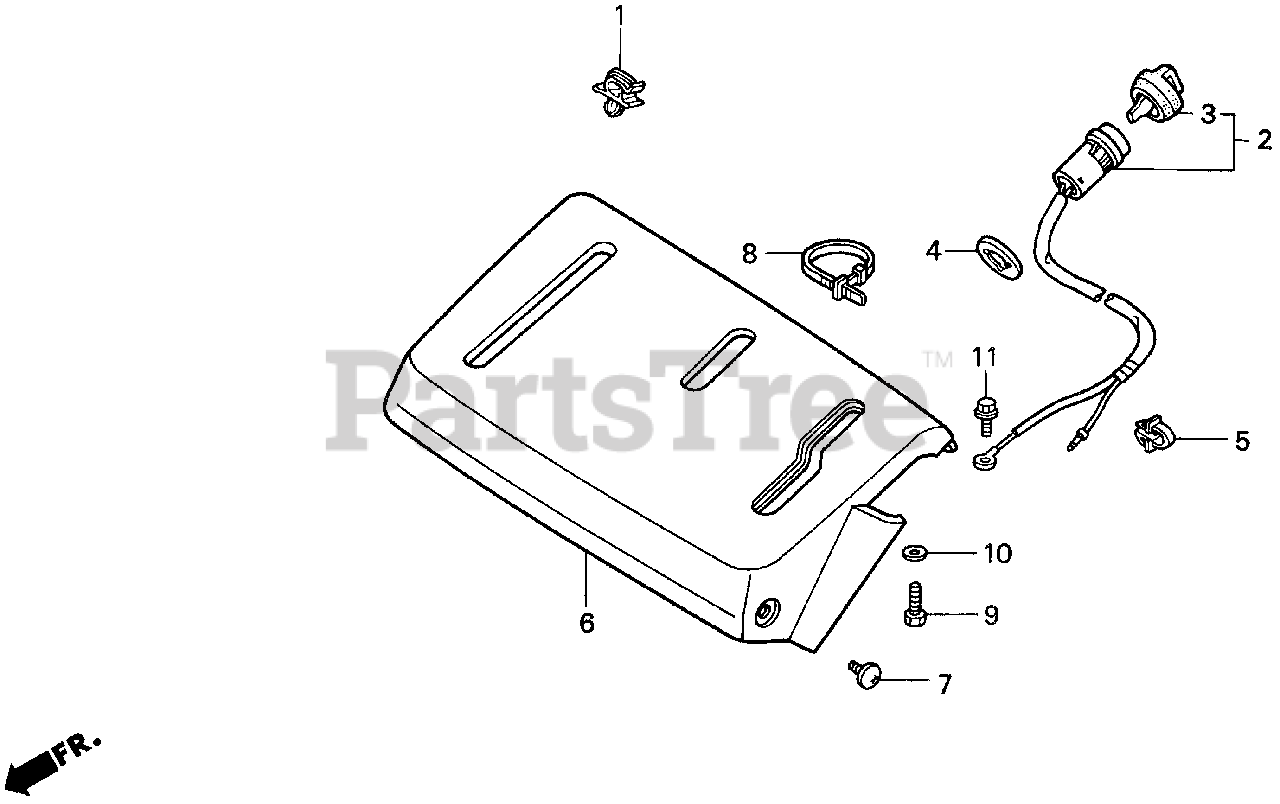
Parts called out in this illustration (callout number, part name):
2	SWITCH ASSY., COMBINATION
3	KEY ASSY., COMBINATION SWITCH (RED)
4	SPACER, ENGINE STOP SWITCH
5	HOLDER, STOP SWITCH WIRE
6	PANEL, CONTROL *NH296* (ALPS GRAY)
7	SCREW, METER VISOR SETTING
8	BAND, WIRE (95MM)
8	BAND, WIRE HARNESS
9	BOLT, HEX. (5X12)
10	WASHER, PLAIN (5MM)
11	BOLT, FLANGE (6X10)
